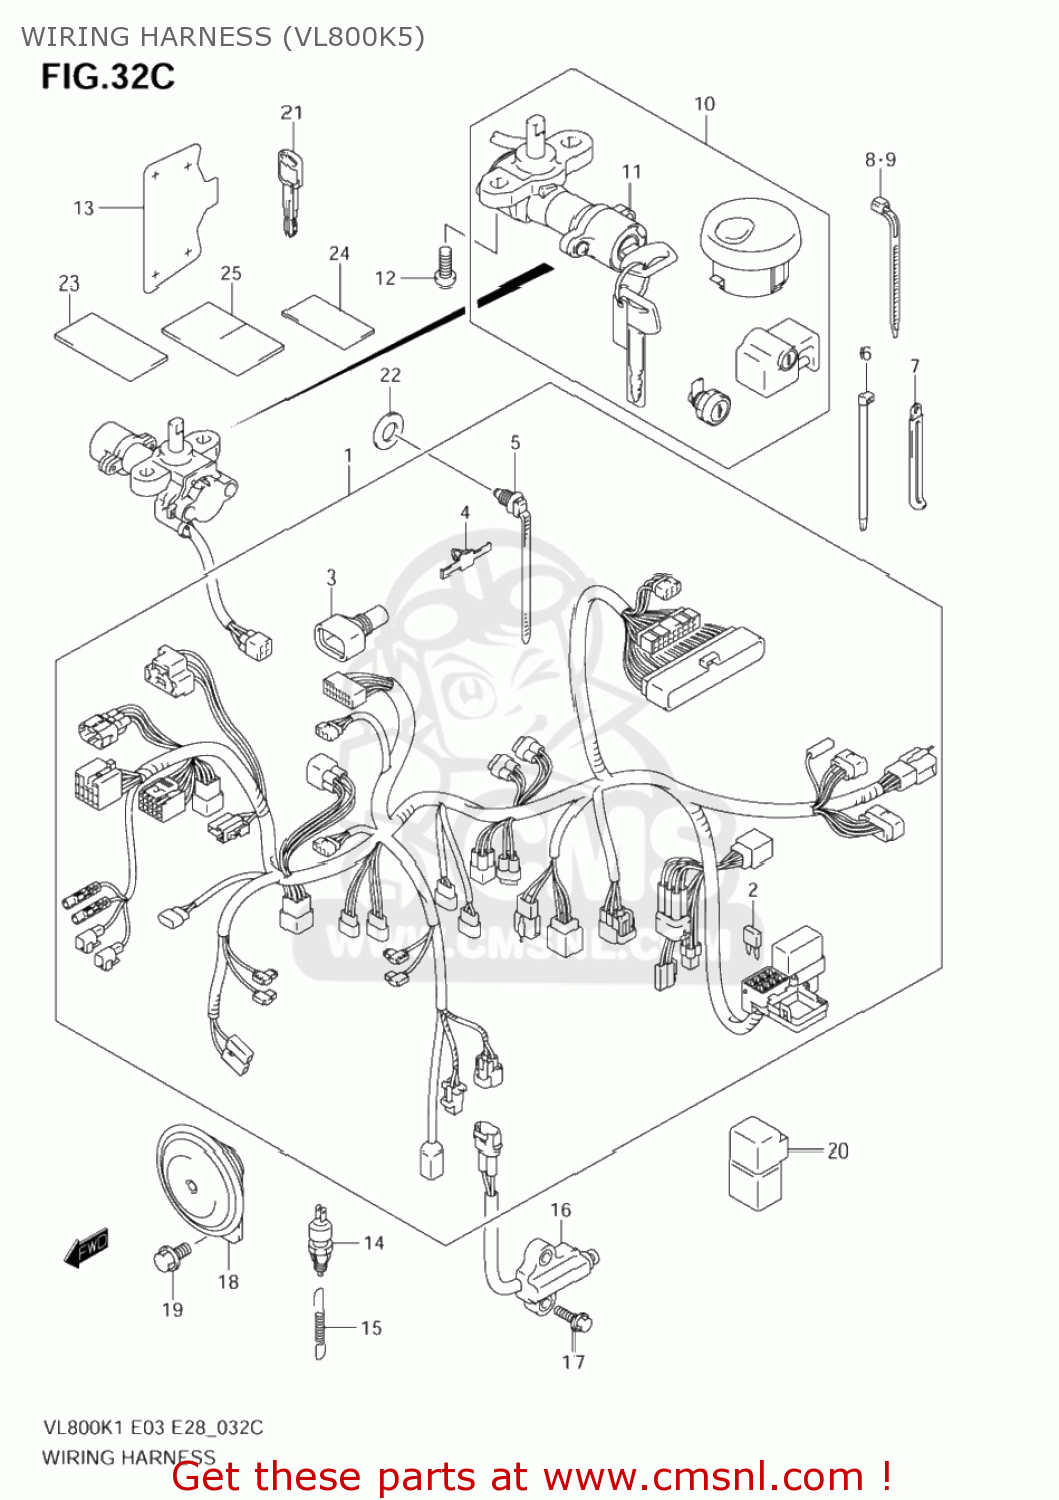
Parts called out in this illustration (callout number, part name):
1	HARNESS,WIRING
2	FUSE(10A)
3	COVER,SPEEDOMETER COUPLER
4	CLAMP
5	CLAMP(L:154)
6	CLAMP(L:145)
7	CLAMP(L:80)
8	CLAMP(L:165)
9	CLAMP(L:190)
10	LOCK SET
11	LOCK ASSY,STEERING
12	BOLT(8X20)
13	PROTECTOR,IGNITION SWITCH
14	SWITCH ASSY,STOP LAMP
15	SPRING
16	SWITCH ASSY,SIDE STAND
17	BOLT
18	HORN ASSY
19	BOLT
20	RELAY ASSY
21	KEY,BLANK
22	WASHER(6.5X16X1.2)
23	TAPE,WIRING HARNESS(28X50X0.13
24	PROTECTOR(30X30X3)
25	PROTECTOR,HARNESS(30X50X3)
